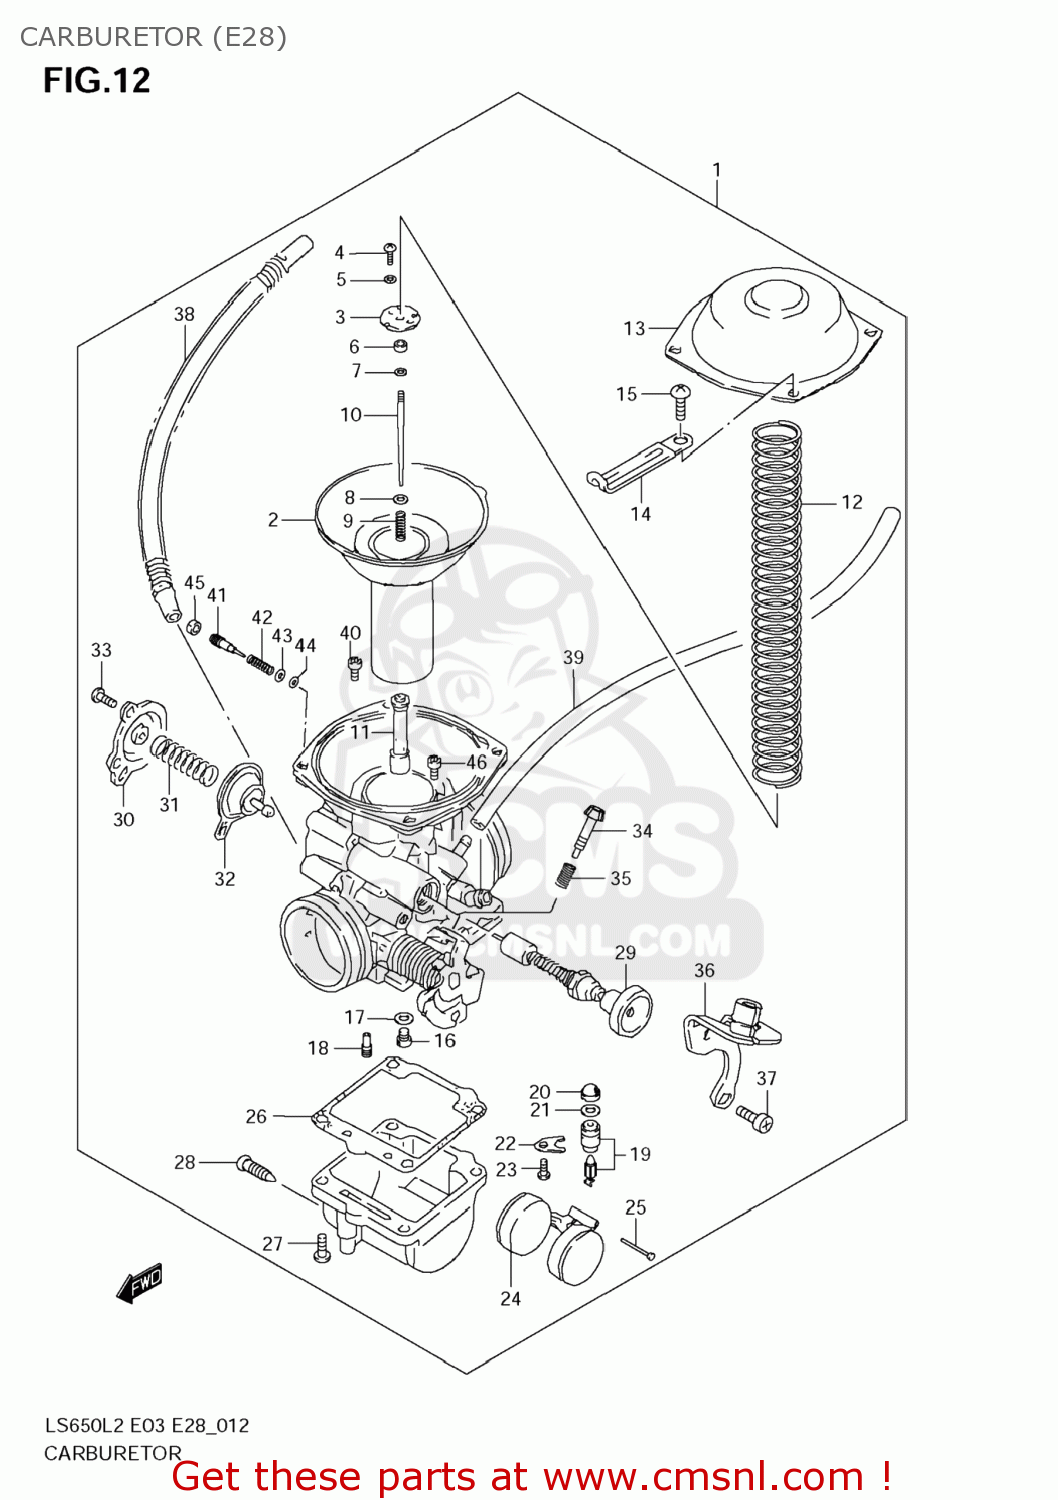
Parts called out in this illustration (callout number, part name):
1	CARBURETOR ASSY
2	DIAPHRAGM ASSY
3	PLATE
4	SCREW
5	WASHER,LOCK
6	RING
7	CLIP,NEEDLE
8	WASHER
9	SPRING
10	NEEDLE,JET(5C17)
11	JET,NEEDLE(X-7M)
12	SPRING
13	COVER
14	CLAMP(L:80)
15	SCREW
16	JET,MAIN(145)
17	WASHER
18	JET,PILOT(52.5)
19	VALVE ASSY,NEEDLE
20	FILTER
21	O RING,NEEDLE VALVE SEAT
22	PLATE
23	SCREW
24	FLOAT
25	PIN,FLOAT
26	GASKET,FLOAT CAHMBER (NAS)
27	SCREW
28	SCREW,DRAIN
29	PLUNGER ASSY
30	COVER
31	SPRING
32	DIAPHRAGM ASSY
33	SCREW
34	ADJUSTER
35	SPRING
36	BRACKET ASSY
37	SCREW
38	HOSE ASSY
39	HOSE(5X8.2X600)
40	JET,PILOT(230)
41	SCREW,AIR
42	SPRING
43	WASHER
44	O RING,PILOT AIR SCREW
45	PLUG
46	JET(45)
